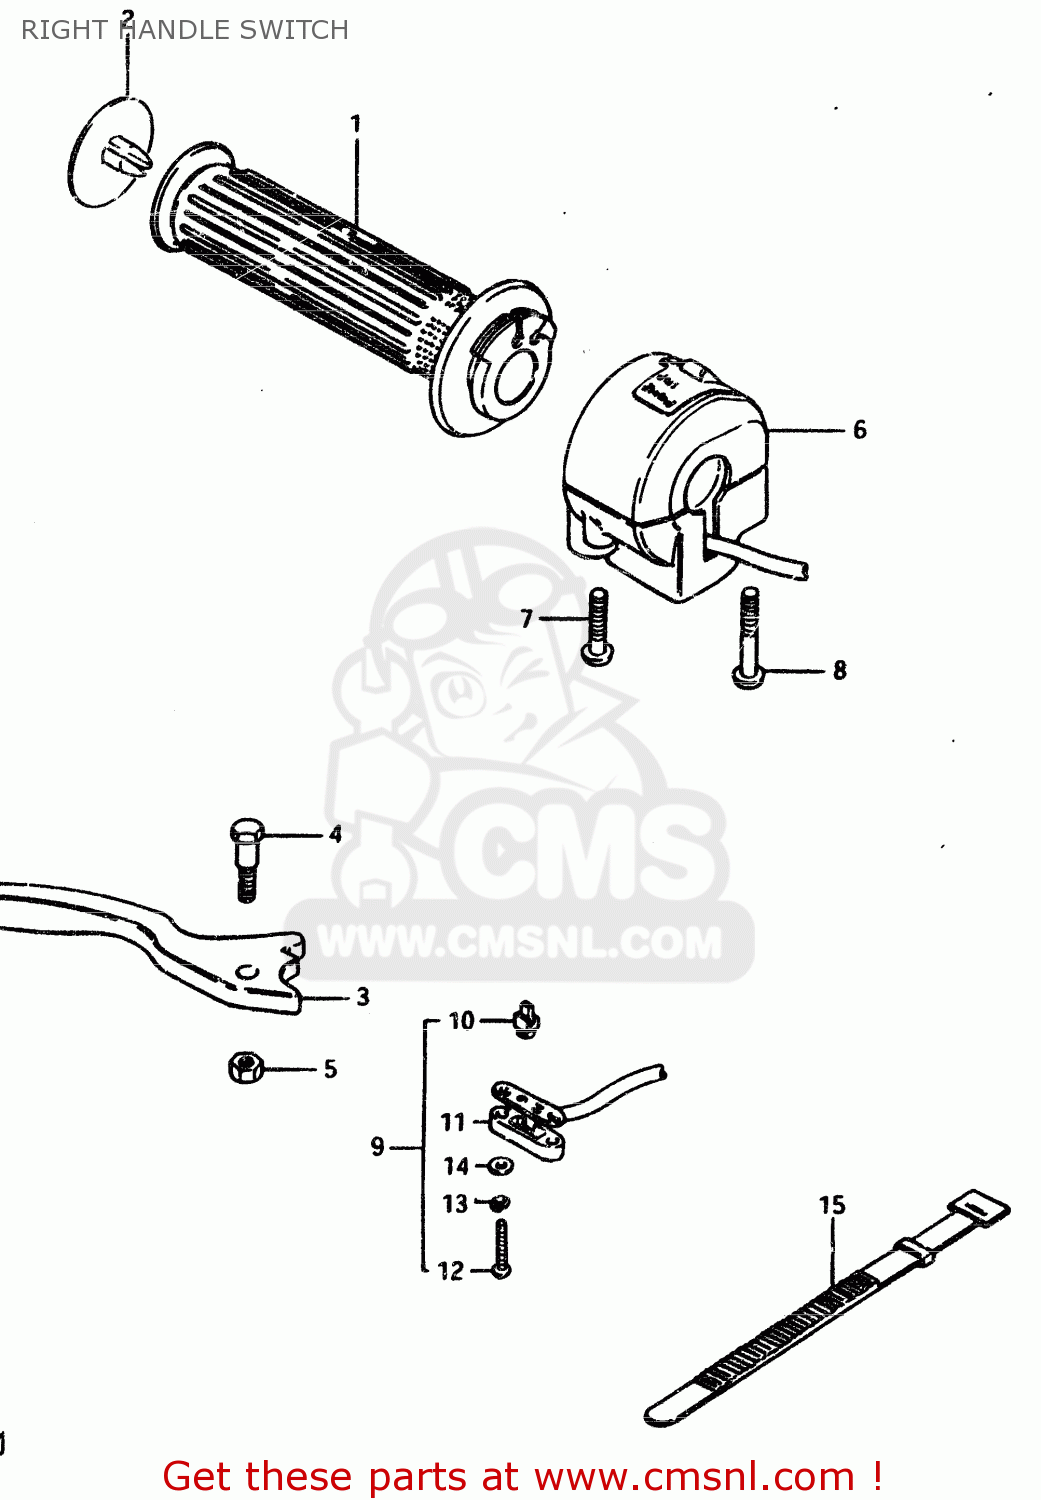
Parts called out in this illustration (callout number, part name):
1	GRIP,THROTTLE
2	CAP,GRIP END
3	LEVER,BRAKE
4	BOLT
5	NUT 6MM
6	SWITCH ASSY,HA
7	SCREW
8	SCREW
9	SWITCH ASSEMBLY
10	CONTACT,SWITCH
11	COVER,FR BK TERMINAL BASE
12	SCREW
13	LOCK WASHER
14	WASHER
15	CLAMP(L:120)
